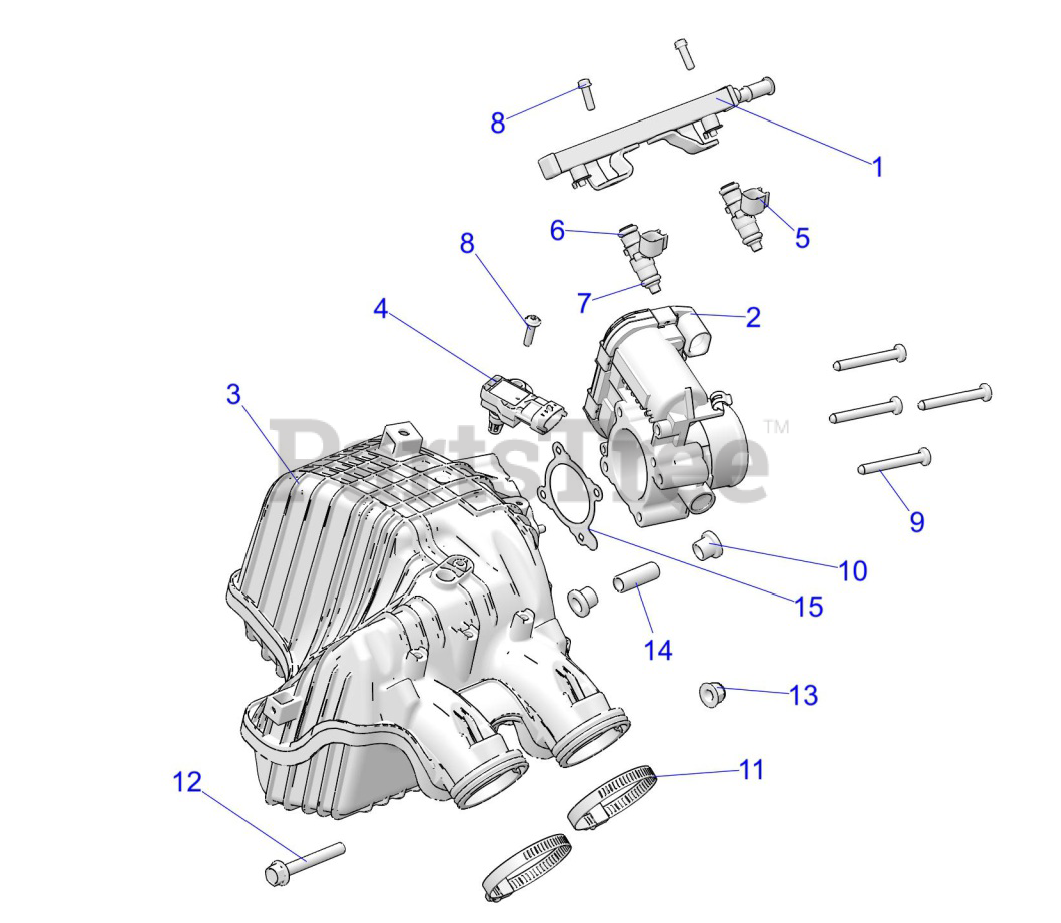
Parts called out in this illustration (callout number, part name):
1	RAIL-FUEL,SOHC
2	THROTTLE-ETC,46MM
3	MANIFOLD-INTAKE,SOHC
4	SENSOR-TMAP DSS3-TF
5	INJ-FUEL,SE
6	O-RING BOSCH,EV-SE,UPPER
7	O-RING BOSCH,EV-SE,LOWER
8	SCR-M6X20,HXFLG,0600214
9	SCR-M6X1.0X50.0 HX/FL-YD (10)
10	BUSHING-MOUNT
11	CLAMP,BAND,NARROW (10)
12	SCR-HXFL-M8X1.25X60 8.8 ZOD
13	NUT-M8X1.25,FLG,NYLOC-OLIVE D
14	SHAFT-COMPRESSION LMTR,34.4MM
15	GASKET-ETC
